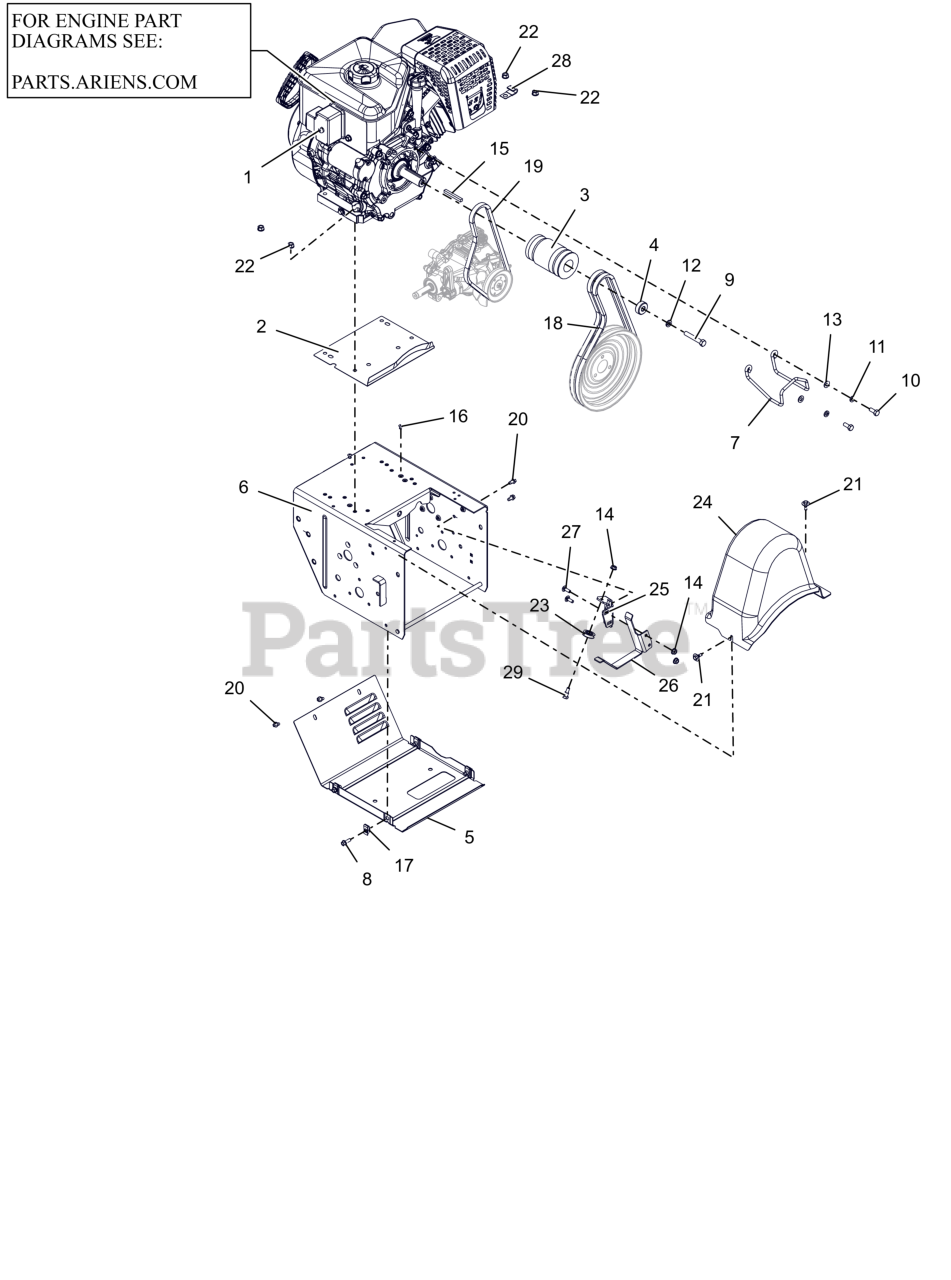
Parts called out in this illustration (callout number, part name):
1	ENGINE, EFI 420 GEN 3 240V/60W
2	BAFFLE, WATER - LARGE BLOCK
3	SHEAVE, COMBO HYDRO WHEEL 4L
4	BSHG, SPCR .406 X 1.250 X .500
5	COVER, BOTTOM - VENTILATED
6	FRAME, MAIN - PRO (WELDMENT)
7	FINGER, BELT
8	BLT, HWH .25-20X.75 G5 ZCC
9	BLT, HEX .38-24X2.25 G5 ZCC
10	BLT-HEX .44-14X1.00 GR5
11	WSHR, LK-HVY .312X.097 ZCC
12	WSHR,LK-REG .375X.094 ZCC
13	WSHR,FLT .344X.688X.065 ZCC
14	NUT-LK-TOP-FLG .250-20 GF ZCC
15	KEY .25X.25X2.25
16	RVT, POP .1875 ZCC
17	NUT-RTNR .25-20X.56
18	V-BELT, HA-RAW EDGE (SET)
19	V-BELT, 4L-WRAPPED
20	SCR-TAP .25-20X.50 HWH ZCC
21	SCR-TAP .25-20X.5 CAPTIVE
22	NUT,LK-CTR-FLG .31-18 GF ZCC
23	PULLEY, CABLE
24	COVER, BELT-LARGE
25	BRACKET, CLUTCH CABLE
26	FINGER, BELT - FLAT
27	BLT, RHSN .25-20X.750 G5 ZCC
28	J-CLAMP
29	BOLT, SHLDR -.375 X .375 X .25-20
